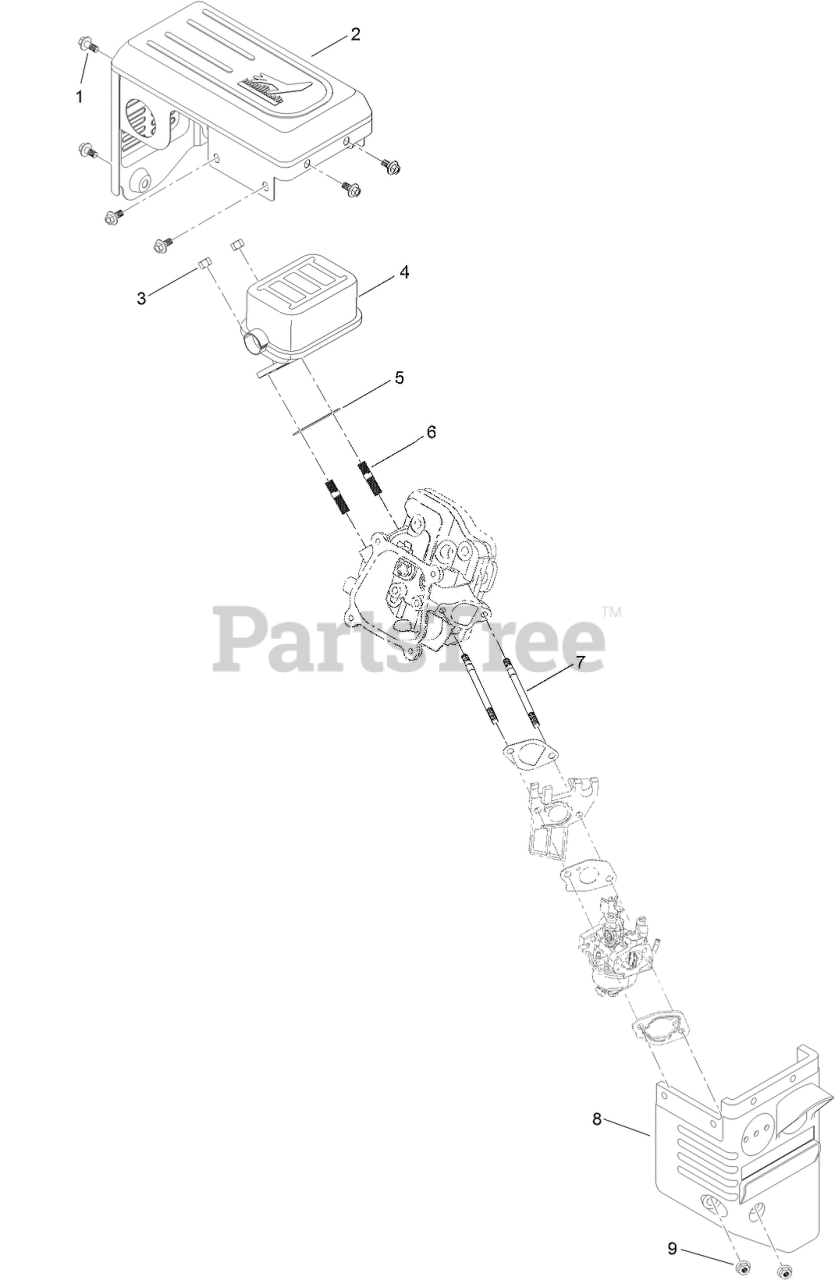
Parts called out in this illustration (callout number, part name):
1	SCREW-HHF
2	GUARD-MUFFLER
3	NUT-HH
4	MUFFLER ASM
5	GASKET-EXHAUST
6	STUD-EXHAUST
7	STUD-INTAKE
8	BOX-HEATER
9	NUT-FLANGE
